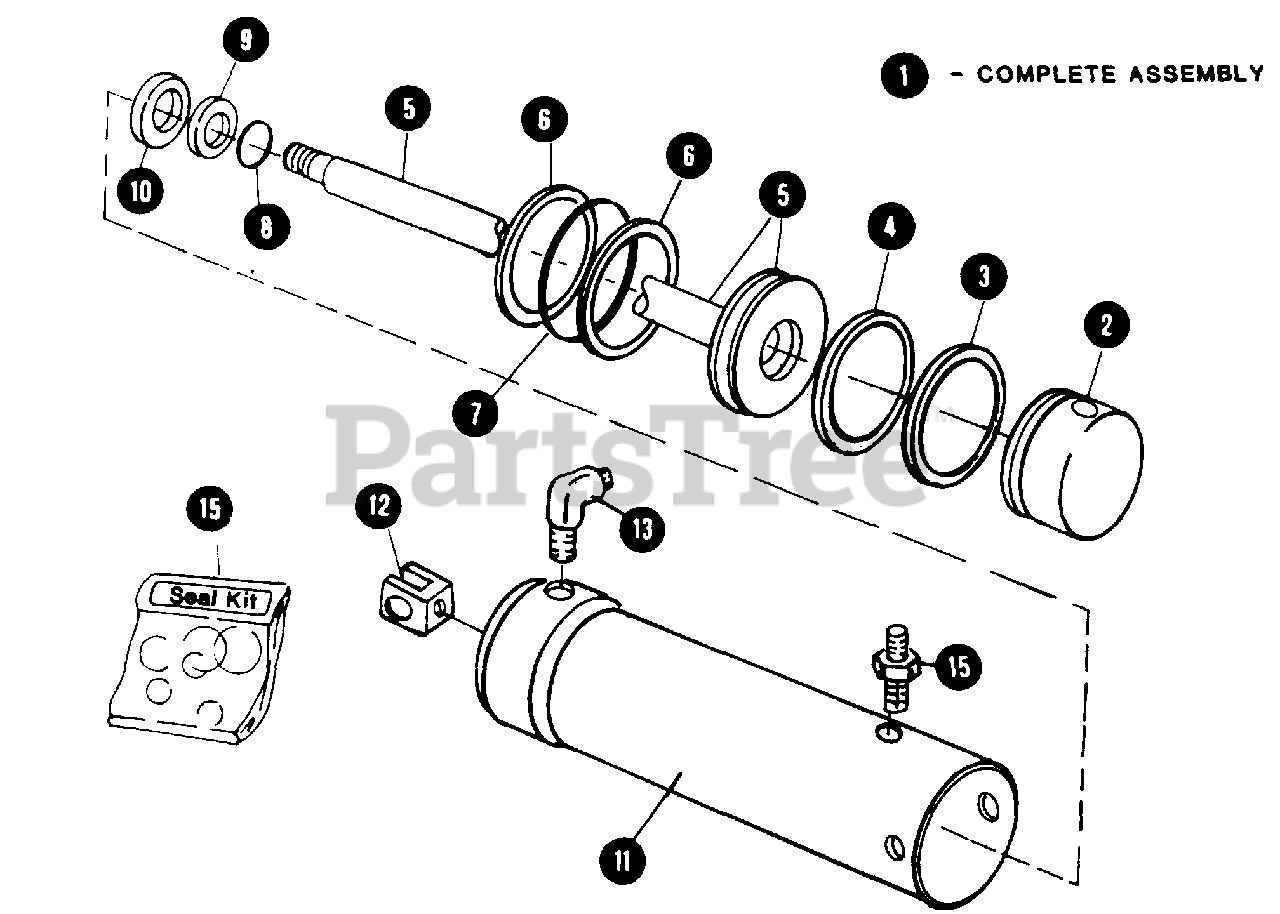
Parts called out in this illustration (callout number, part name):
1	CYLINDER, REAR LIFT ASSEMBLY
2	HEAD, CYLINDER
3	WASHER, HEAD O-RING BACK-UP
4	O-RING, CYLINDER HEAD
5	PISTON-ROD ASSEMBLY
6	WASHER, PISTON O-RING BACK-UP
7	O-RING, PISTON
8	O-RING, PISTON ROD SEAL
9	WASHER, SEAL O-RING BACK-UP
10	WIPER, PISTON ROD
11	TUBE CYLINDER
12	FITTING, PISTON ROD END
13	ELBOW, 1/4 P.T. 90°
15	FITTING, CONNECTOR 1/4 P, T. x 9/16-18 STRAIGHT THREAD
